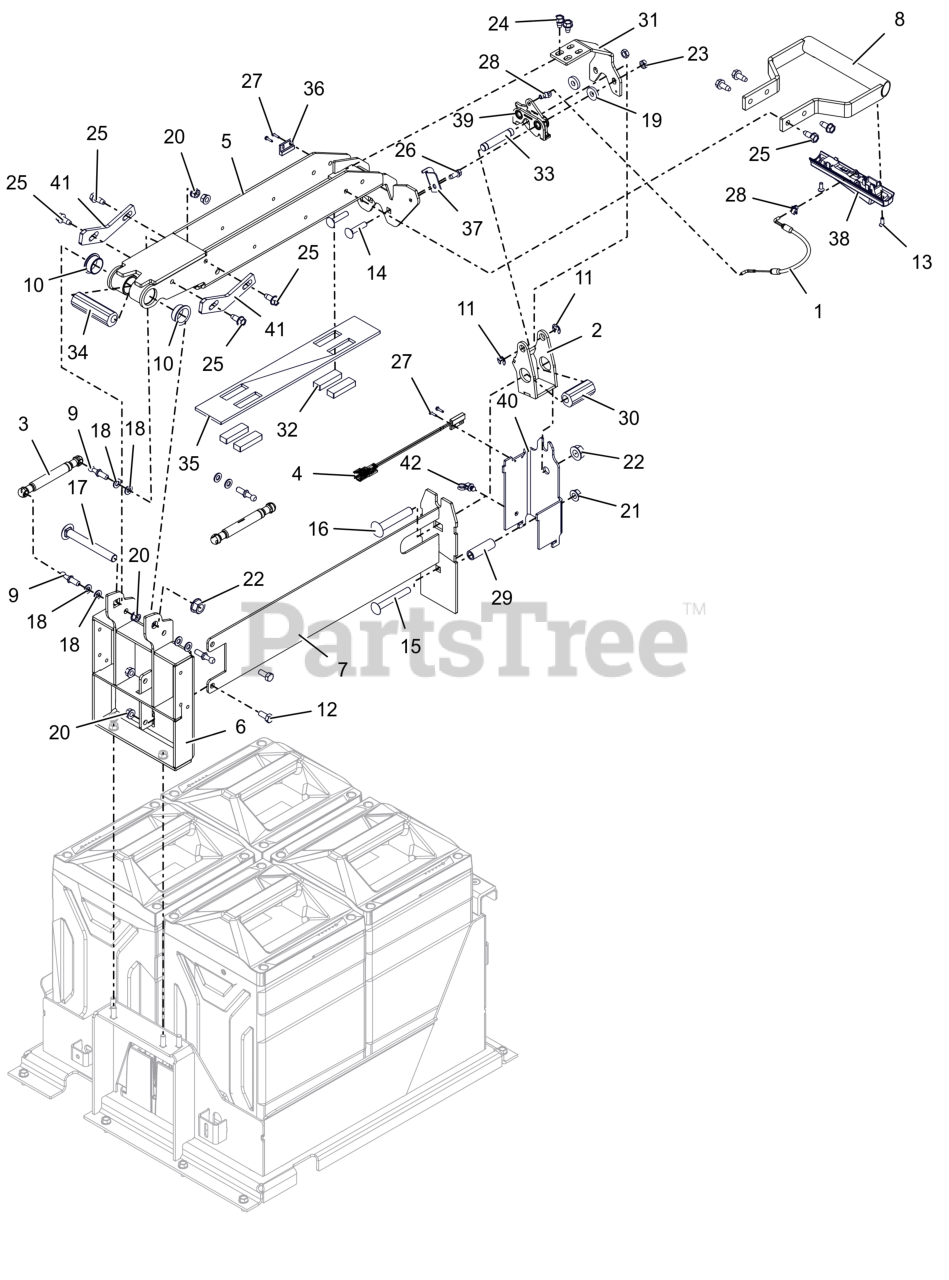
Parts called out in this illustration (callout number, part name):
1	CABLE, HOOD RELEASE
2	WLDMT, ECCENTRIC
3	DAMPER, GAS
4	SWITCH, MAGNETIC
5	WLDMT- HOLDOWN MAIN
6	WLDMT- PIVOT BATTERY HOLDDOWN
7	WLDMT- ECCENTRIC MTG
8	WLDMT, HANDLE (ORANGE)
9	STUD-BALL-THREADED
10	BSHG-FLG 1.0X1.125X.50X1.375 R
11	RG-RTNG-EXT .438X.035
12	BLT,HEX .31-18X.75 G5 ZCC
13	SCR, FLCSKH M5-0.8X14 GR10.9 ROHS
14	BLT,RHSN .31-18X1.50 G5 ZCC
15	BTL,RHSSN .375-16 X 3 G5 ZCC
16	BTL,RHSSN .500-13 X 3 G5 ZCC
17	BTL,RHSSN .500-13 X 4.25 G5 ZCC
18	WSHR,FLT .323X.625X.062 ZCC
19	WSHR, FLT .328X.870X.179 ZCC
20	NUT,LK-CTR-FLG .31-18 GF ZCC
21	NUT-LK-CTR-FLG .375-16 GF ZCC
22	NUT-LK-CTR-FLG .500-13 GG ZCC
23	NUT-LK-CTR-JAM .312-18 GB ZCC
24	SCR,TAP .312-18X.50 HWH TR ZCC
25	SCR,TAP .312-18X.75 HWH TR ZCC
26	SCR,TAP .25-20X.625 HWH ZCC
27	SCR-TAP #4-40x.50 HWH ZCC
28	CLIP, RETAINER
29	SPCR, LATCH BRKT (BLACK)
30	ECCENTRIC, HOOD LATCH
31	BRKT, LATCH MTG (ORANGE)
32	PAD, RUBBER
33	ROD, LATCHING
34	ECCENTRIC, HOOD LATCH-FRONT
35	PAD, RUBBER
36	SWITCH, MAGNET (NO WIRE)
37	RETAINER, CABLE (BLACK)
38	HANDLE, SQUEEZE ACTUATOR
39	LATCH, PUSH TO CLOSE
40	BRKT, ECCENTRIC MTG (ORANGE)
41	STOP, HOOD (BLACK)
42	CABLE TIE W/ TREE (.25 HOLE)
